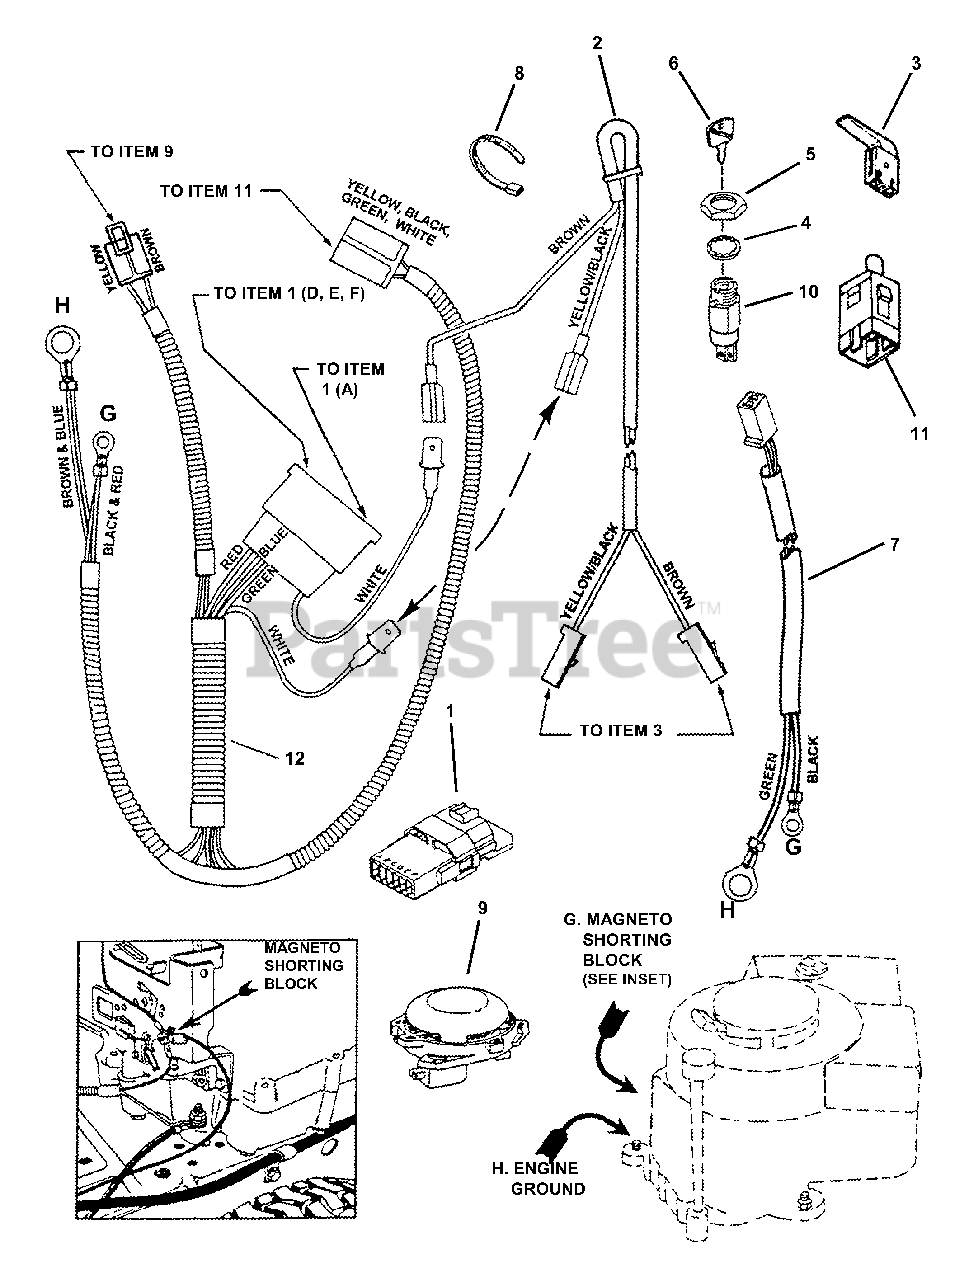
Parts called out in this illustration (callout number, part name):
1	INTERLOCK, Module
2	HARNESS, Deck Interlock
3	SWITCH, Deck Interlock (NO)
4	WASHER, 5/8 Internal Tooth Lock
5	NUT, 5/8-32 Hex
6	KEY, Switch (2)
7	HARNESS, Ground (Recoil Start)
8	TIE, 7" Long Cable (3)
9	SWITCH, Seat (NC)
10	SWITCH, Ignition (2-Pole) (Recoil Start)
11	SWITCH, Traction Operator's Presence (NC/NO)
12	HARNESS, Operator's Presence Control
